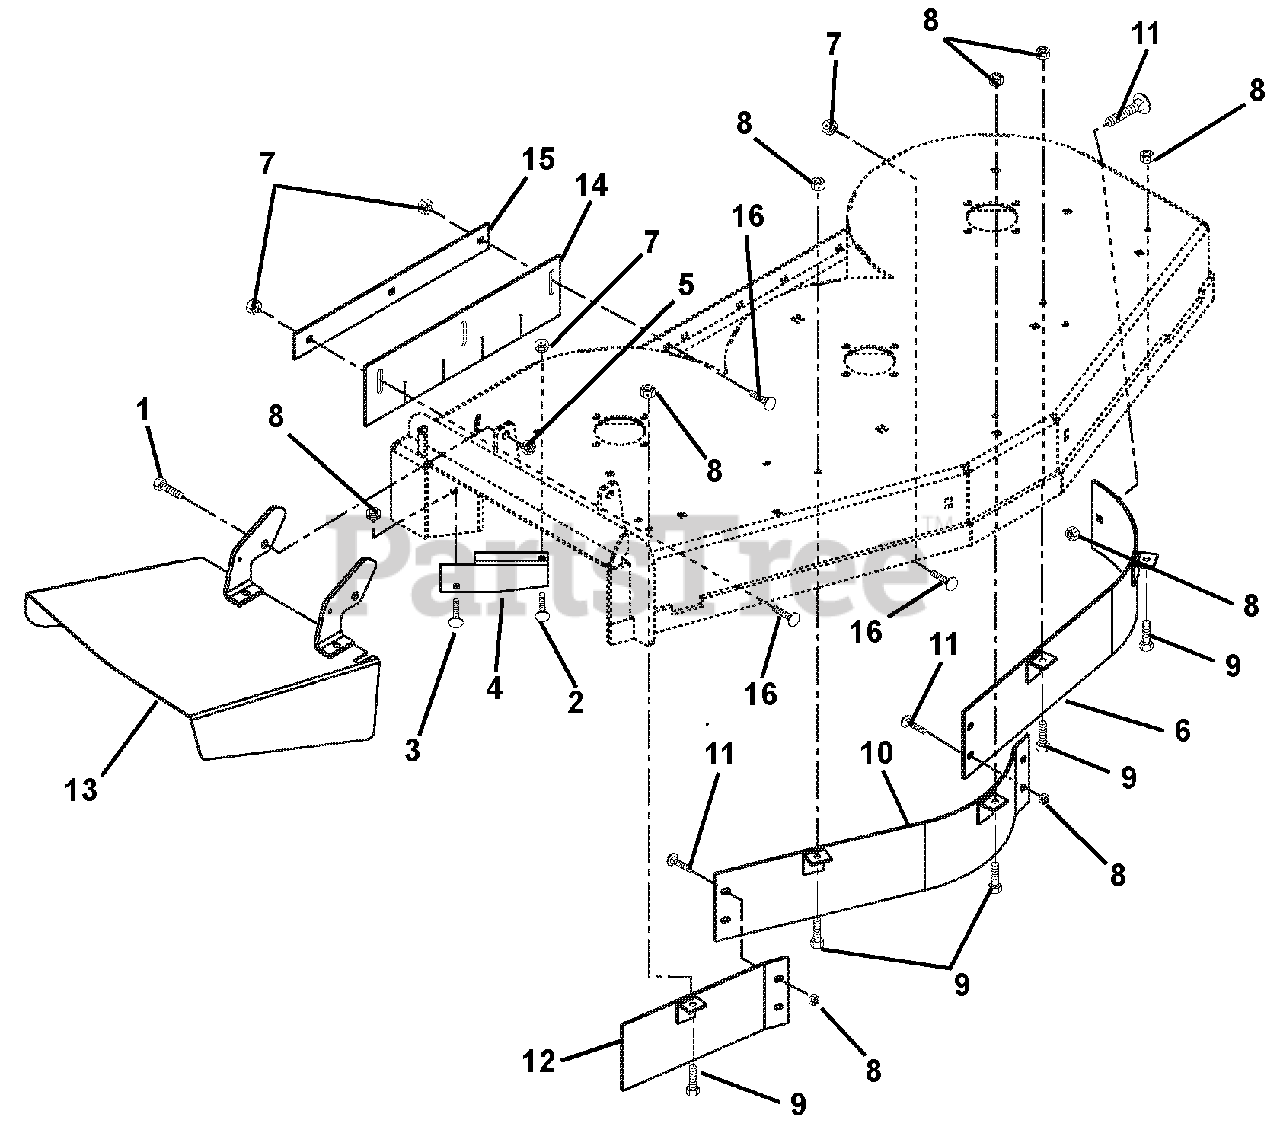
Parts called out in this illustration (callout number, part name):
1	Bolt-Hex .50-13 x 1.25 Grade 5
2	Bolt-Round Head Square Neck .38-16 x .75 Grade 5
3	Bolt-Round Head Square Neck .31-18 x 1.00 Grade 5
4	Deflector 44"/48" (106, 108)
5	Nut-Locking-Nylon .50-13
6	Weldment- Upper Baffle Left (106, 108)
7	Nut-Locking-Top-Flange .38-16
8	Nut-Locking-Top-Flange .31-18
9	Bolt-Hex .31-18 x .75 Grade 5
10	Weldment- Upper Baffle Center (106, 108)
11	Bolt-Round Head Square Neck .31-18 x .75 Grade 5
12	Weldment, Right Hand Baffle-Upper (106, 108)
13	Chute-Discharge
14	Skirt- Rubber
15	Strip- Striper Mount
16	Bolt-Round Head Square Neck .38-16 x 1.00 Grade 5
